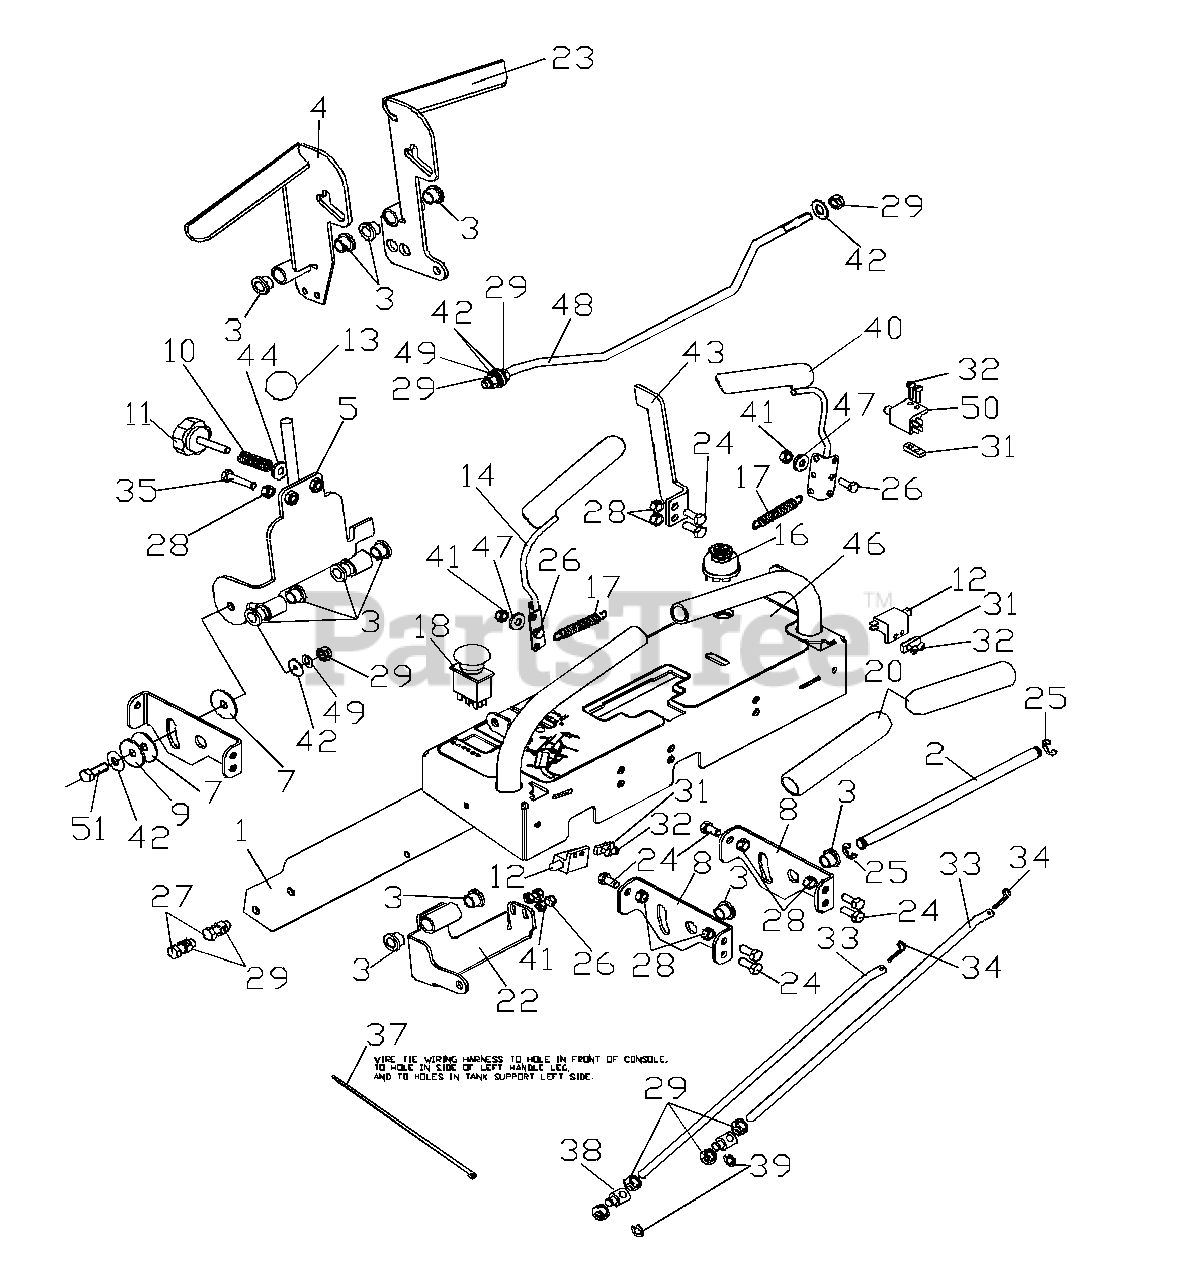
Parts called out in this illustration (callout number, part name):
3	FLANGE BUSHING
4	PADDLE LH.
5	NEUTRAL BAR
7	FRICTION WASHER
8	CROSSBRACE
9	WASHER 1/2 FLAT
12	SWITCH N.C.
14	OP LEVER LH.
16	IGNITION SWITCH
18	CLUTCH SWITCH
22	TAB WLDMT. LH.
23	PADDLE RH.
24	HCS 5/16 X .750
25	E-RING 1/2
26	HCS 1/4 X .625
27	HCS 3/8 X 1.000
28	NUT 5/16 CTR. LOCK
29	NUT 3/8 CTR. LOCK
31	TAPPED PLATE
32	SCREW #10-24
34	COTTER PIN
35	HCS 5/16 X 1.250
40	OP LEVER RH.
41	NUT 1/4 CTR. LOCK
42	WASHER 3/8 FLAT
43	STOP PLATE
44	WASHER 5/16 FLAT
46	CONSOLE DECAL
47	WASHER 1/4 FLAT
48	NEUTRAL BAIL
49	WASHER 3/8 LOCK
50	SAFETY SWITCH
51	HCS 3/8 X 1.250
